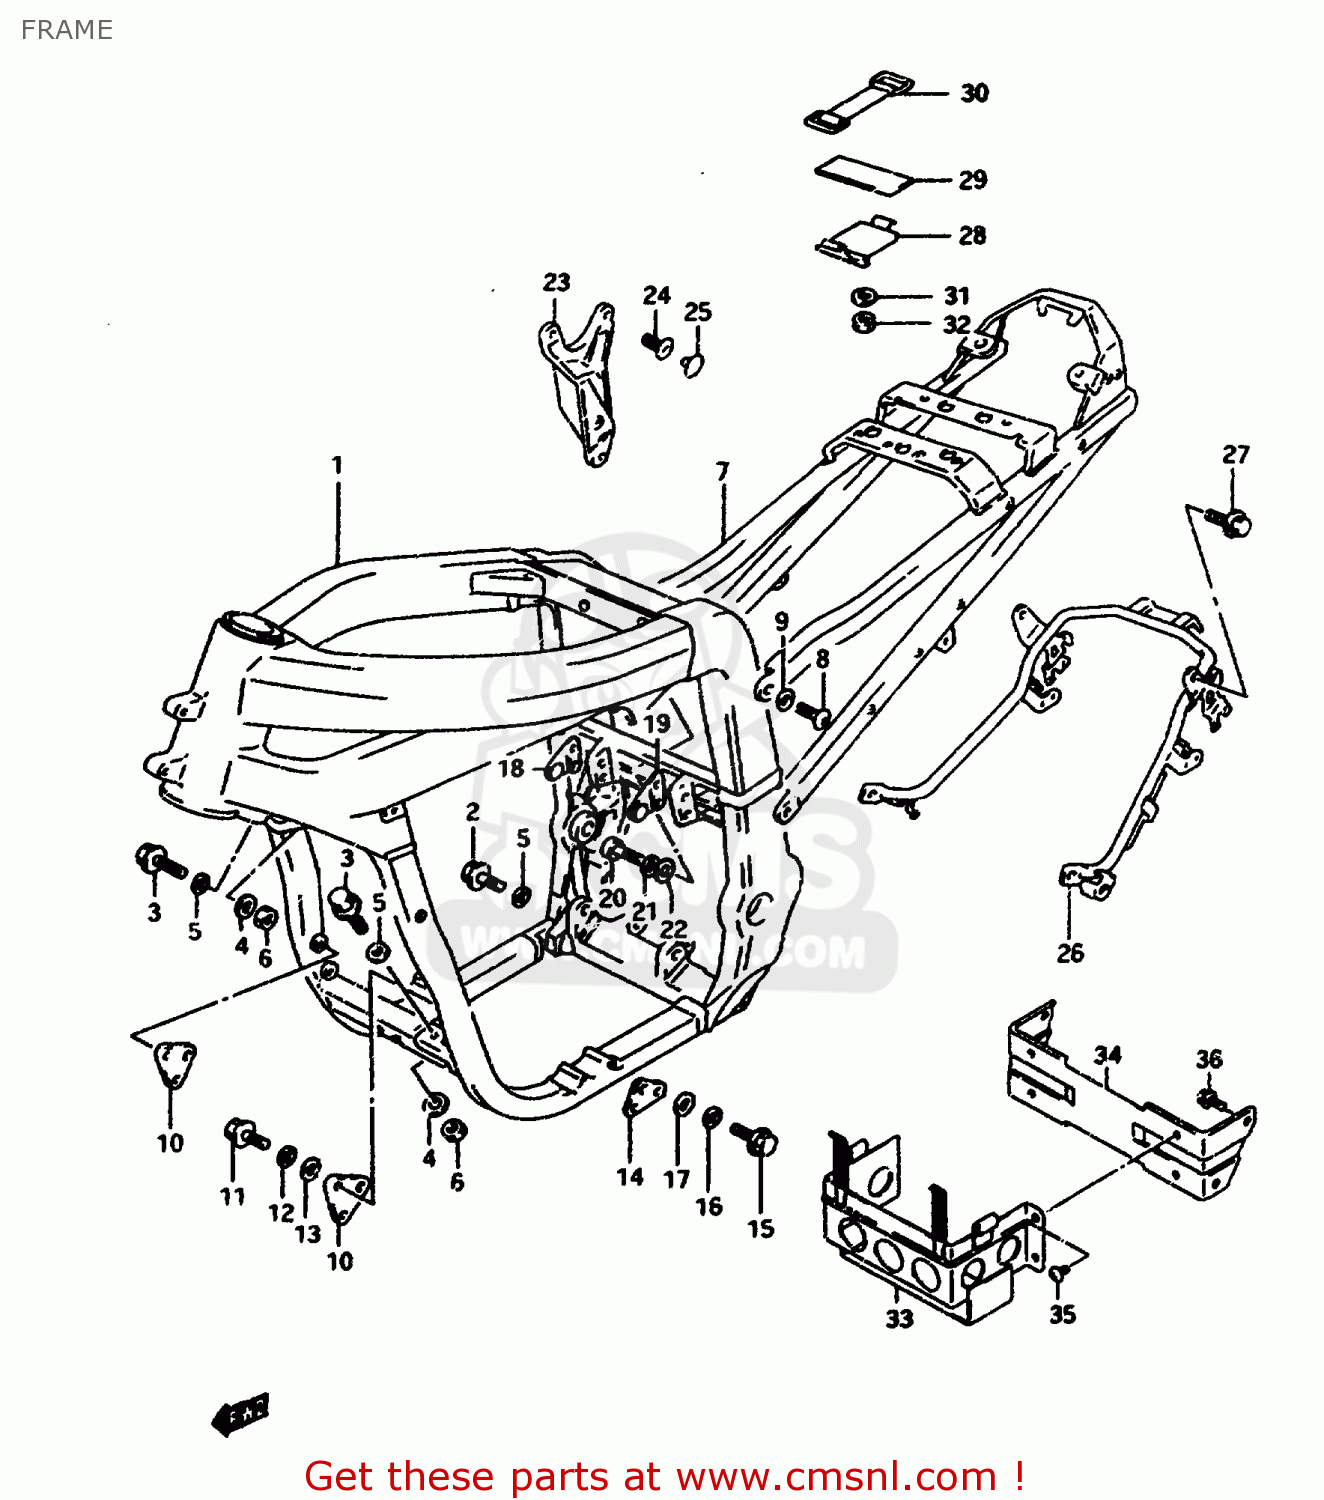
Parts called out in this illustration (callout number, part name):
1	FRAME SET
2	BOLT
3	BOLT
4	WASHER (10.1X21X2.3)
5	WASHER
6	NUT
7	RAIL,SEAT
8	BOLT,FOOTREST BRACKET
9	WASHER
10	PLATE,ENG MTG NO.1
11	BOLT
12	WASHER,LOCK
13	WASHER (8.2X20X1.6)
14	PLATE,ENG MTG NO.2,R
15	BOLT
16	WASHER,LOCK
17	WASHER (8.2X20X1.6)
18	PLATE,ENGINE MOUNTING NO.3
19	PLATE,ENG MTG NO.3,L
20	BOLT(8X22)
21	WASHER,LOCK
22	WASHER (8.2X20X1.6)
23	PLATE,ENG MTG UPR,L
24	BOLT(8X25)
25	CAP(OD:10)
26	GRIP,RR
27	BOLT
28	HOLDER,TOOL
29	COVER,HARNESS
30	BAND
31	WASHER
32	NUT
33	HOLDER,BATTERY
34	BRACKET,BATTERY HOLDER
35	SCREW 6X12
36	BOLT
